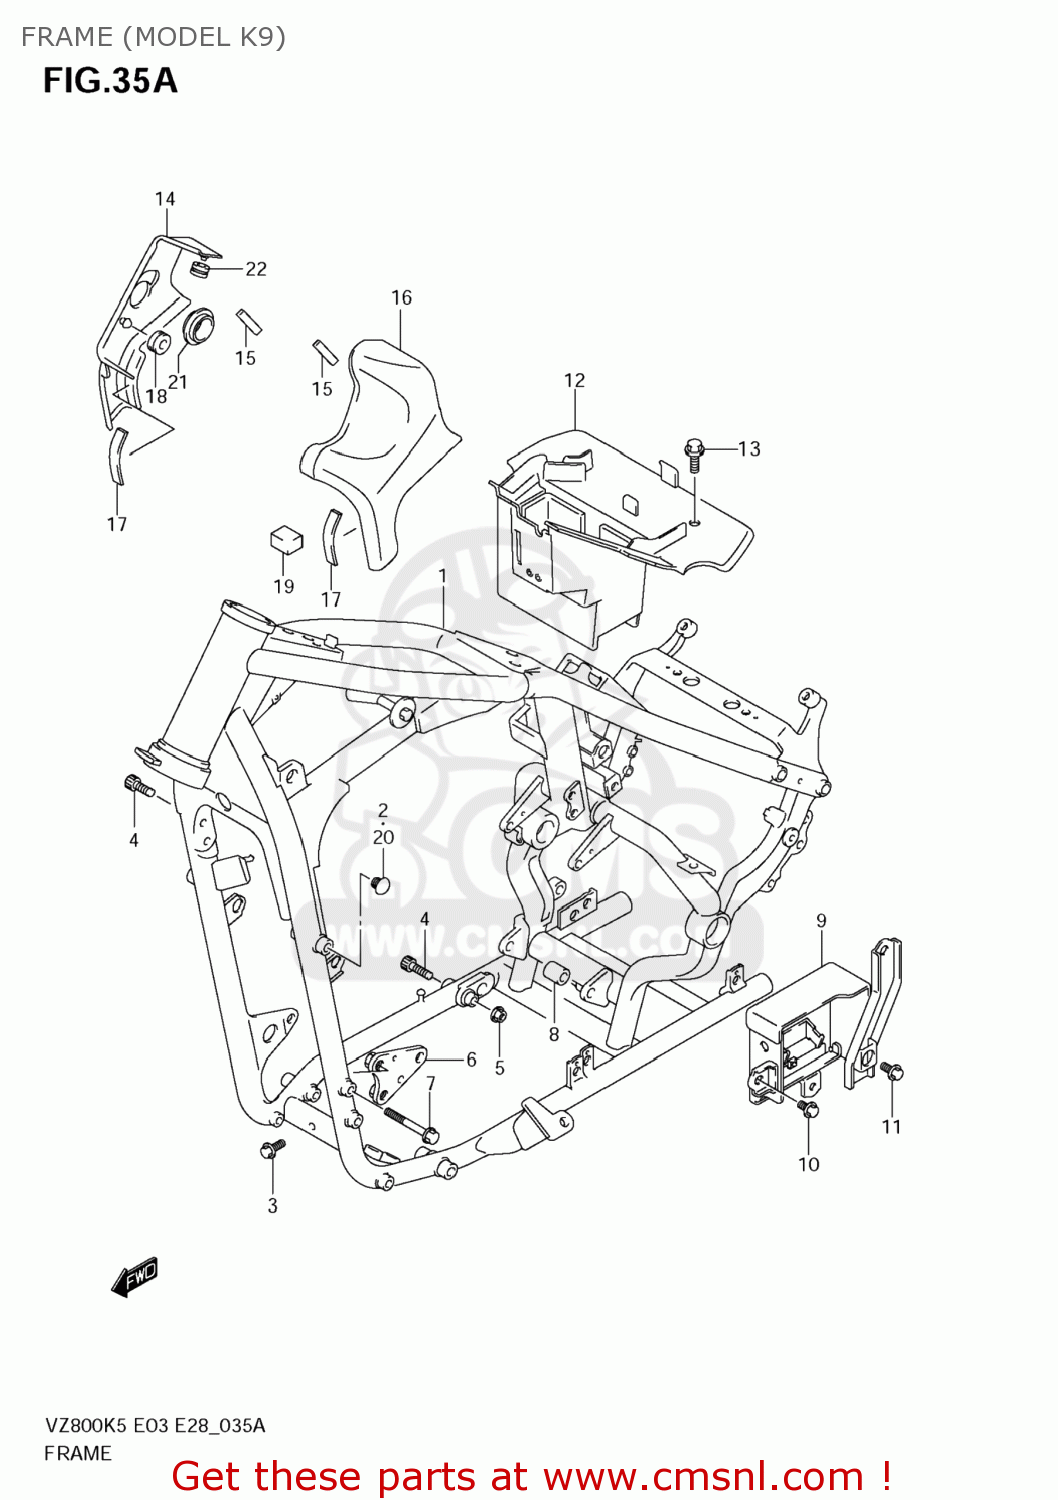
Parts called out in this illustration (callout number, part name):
1	FRAME(BLACK)
2	CAP(OD:14)
3	BOLT
4	BOLT
5	NUT
6	PLATE,ENGINE MOUNT NO.1,L
7	BOLT(8X65)
8	SPACER,ENG MTG LR
9	HOLDER,ELECTRIC PARTS
10	BOLT
11	BOLT
12	HOLDER,ELECTRI
13	BOLT(6X16)
14	COVER,FRAME HEAD,R(BLACK)
15	CUSHION,FR FENDER
16	COVER COMP,FRA
17	CUSHION,FR FENDER
18	CUSHION
19	CUSHION,RADIATOR COVER INNER
20	CAP(OD:14)
21	CAP
22	CUSHION
